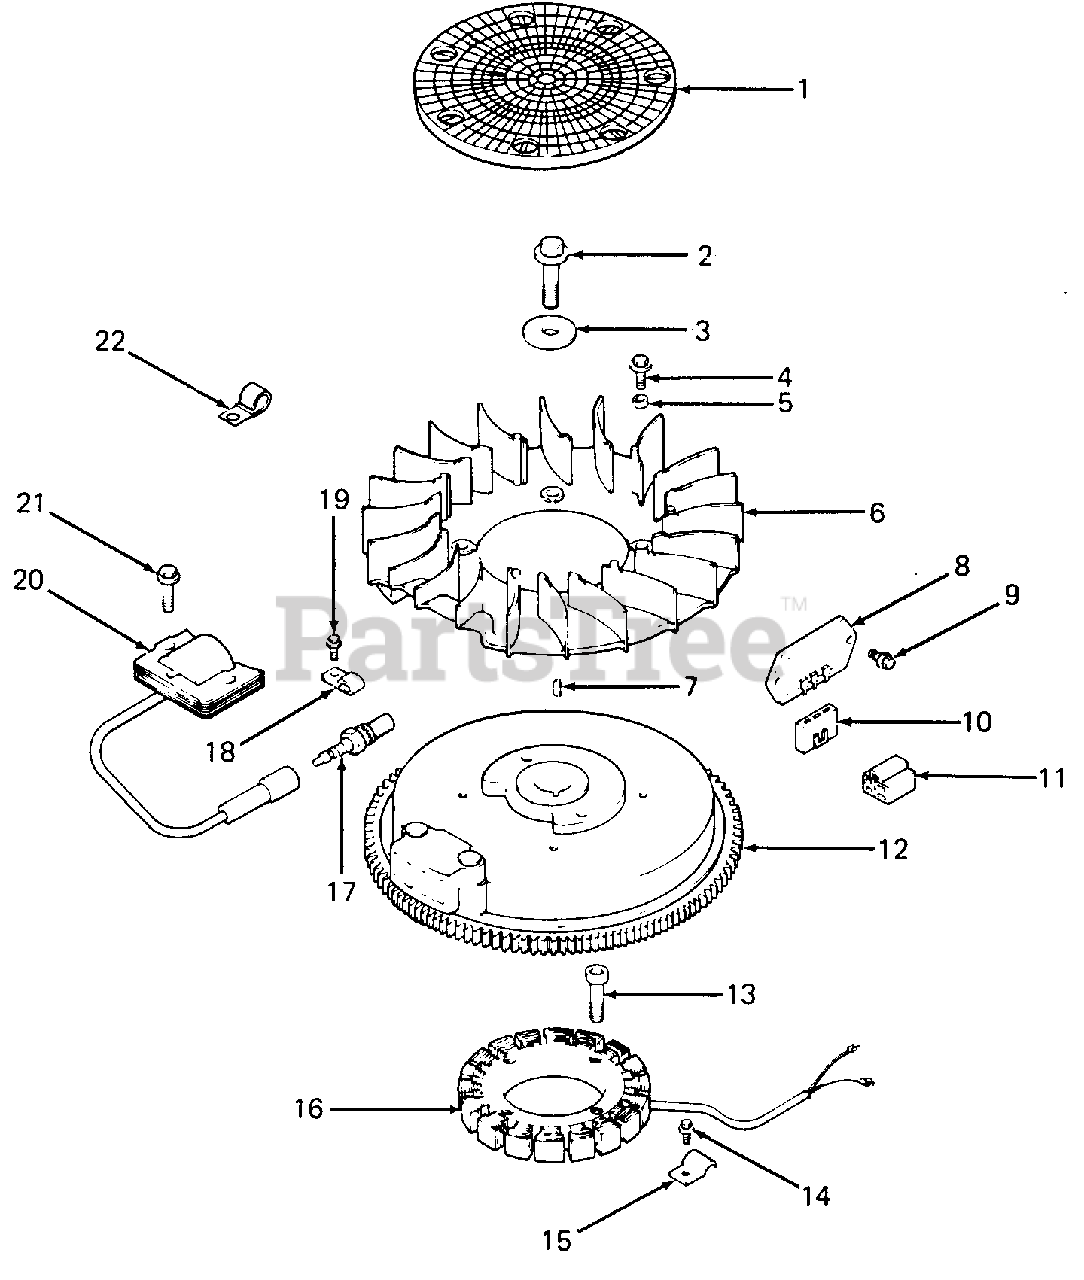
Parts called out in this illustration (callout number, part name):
1	Screen, Rotating Grass
2	Screw, Flywheel, M10 X 1.5 X 45.8
3	Washer, Flywheel, 1-3/8 OD
4	Screw, Fan, M6 X 1.0 X 16
5	Spacer, Fan
6	Fan
8	Rectifier-Regulator
9	Screw, Rectifier-Regulator, M6 X 1.0 X 16
10	Connector, Rectifier-Regulator (3 Contact)
11	Connector (5 Contact)
12	Flywheel
13	Screw, Stator Mounting, M5 X 0.8 X 25
14	Screw, Stator Harness Clip, M5 X 0.8 X 10
15	Clip, Stator Harness
16	Stator, 15 Amp
17	Spark Plug
18	Clip, Kill Lead
19	Screw, Lead Clip, M5 X 0.8 X 10
20	Module, Ignition
21	Screw, Ignition Module, M5 X 0.8 X 20
22	Clip, J
